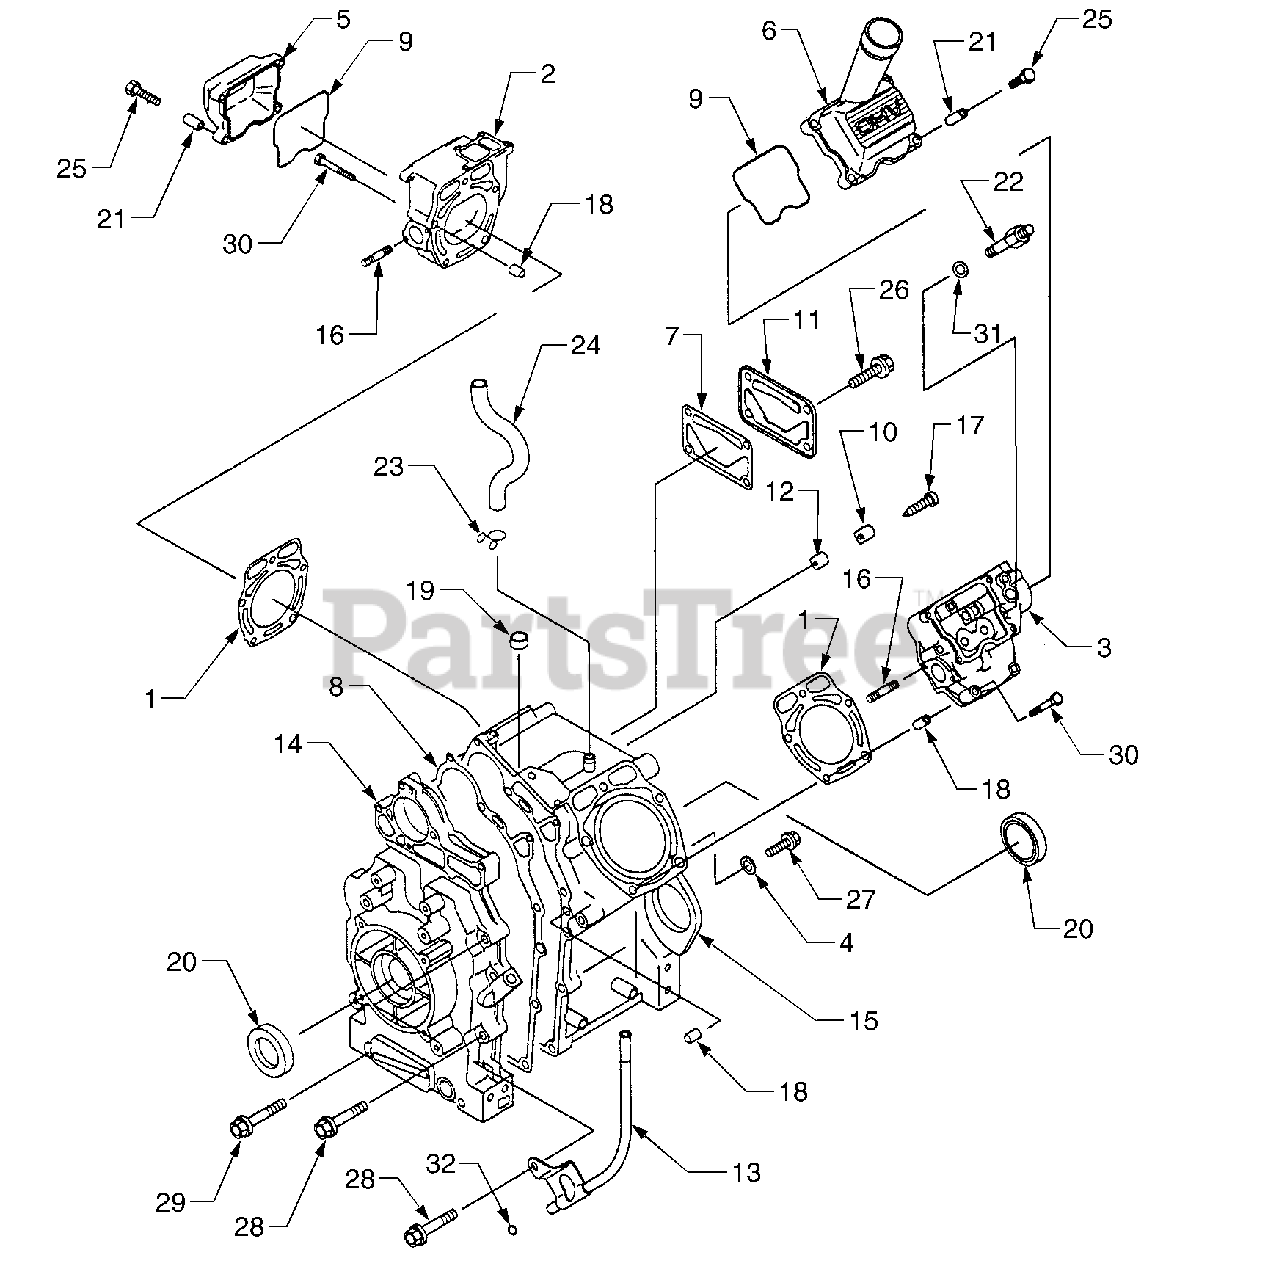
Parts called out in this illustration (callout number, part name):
2	Head, Complete Cylinder
3	Head, Complete Cylinder
6	Cover, Valve w/Oil Fill
7	Gasket, Cover
8	Gasket, Crankcase Cover
9	Gasket, Valve Cover
13	Pipe, Oil Gauge
14	Cover, Crankcase
15	Crankcase Complete
18	Pin, Dowel, M10 x 8.2 x 14
20	Seal, Oil
25	Bolt, Flanged, M6 x 25
26	Bolt, Flanged, M8 x 16
27	Bolt, Flanged, M8 x 12
28	Bolt, Flanged, M8 x 45
29	Bolt, Flanged, M8 x 60
30	Bolt, Flanged, M8 x 65
31	Washer, Plain, 8MM
32	O-Ring, 10MM
